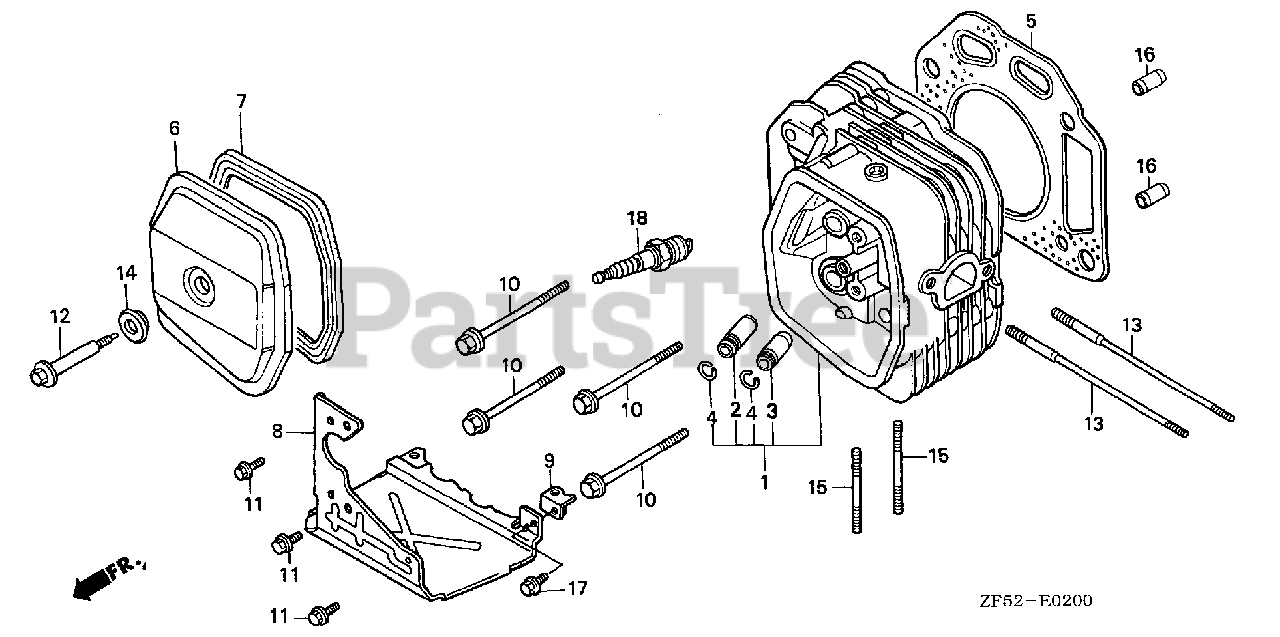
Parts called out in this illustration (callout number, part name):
1	CYLINDER HEAD
2	GUIDE, VALVE (OVER SIZE)
3	GUIDE, EX. VALVE (OVER SIZE)
4	CLIP, VALVE GUIDE
5	GASKET, CYLINDER HEAD
6	COVER, HEAD
7	GASKET, HEAD COVER
8	COVER (LOWER)
9	STAY, COVER (LOWER)
10	BOLT, FLANGE (10X85)
11	BOLT, FLANGE (6X12) (CT200)
12	BOLT, HEAD COVER
13	BOLT, STUD (8X131.5)
14	WASHER, HEAD COVER
15	BOLT, STUD (8X32)
16	PIN, DOWEL (12X20)
17	BOLT, FLANGE (6X12)
18	SPARK PLUG (BPR5ES) (NGK)
